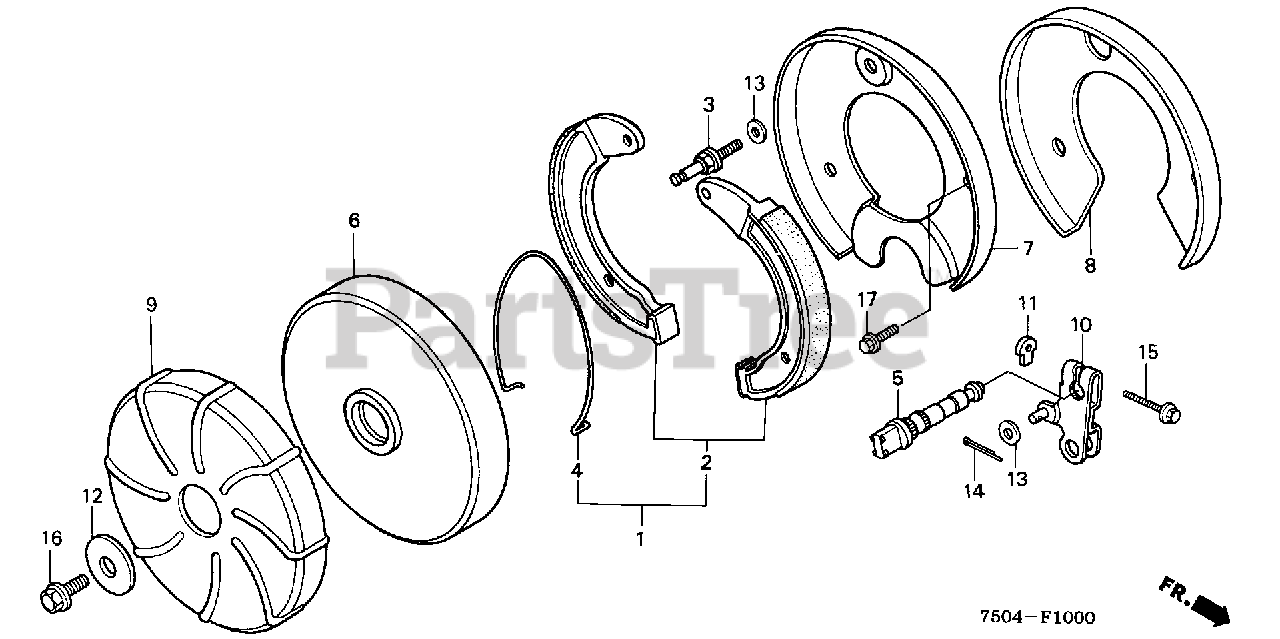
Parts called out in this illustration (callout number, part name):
1	SHOE SET, BRAKE
2	SHOE SET, BRAKE
3	PIN, BRAKE SHOE ANCHOR
4	SPRING, BRAKE SHOE
5	CAM, BRAKE (NOT AVAILABLE)
6	DRUM, BRAKE
7	COVER, BRAKE
8	INSULATOR, BRAKE COVER
9	FIN, BRAKE DRUM
10	ARM, RR. BRAKE
11	NUT, FR. BRAKE ARM SETTING
12	WASHER (10.5MM)
12	WASHER (10X40)
13	WASHER, PLAIN (8MM)
14	PIN, COTTER (2.0X15)
15	BOLT, FLANGE (6X32)
16	BOLT, FLANGE (10X28)
17	BOLT, FLANGE (6X12)
